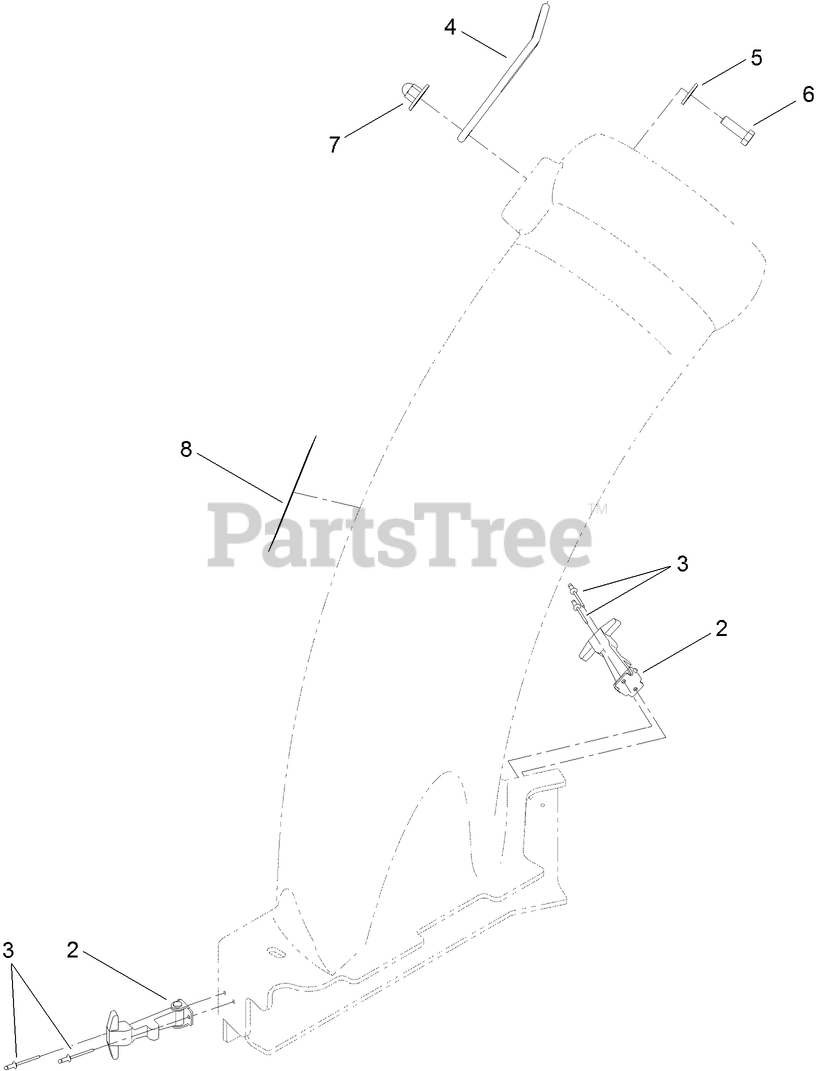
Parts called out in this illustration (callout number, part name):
2	HANDLE ASM
3	RIVET-POP
4	RETAINER-DUCT
5	WASHER-FLAT
6	SCREW-HH
7	NUT-IMPELLER
8	DECAL-DANGER
